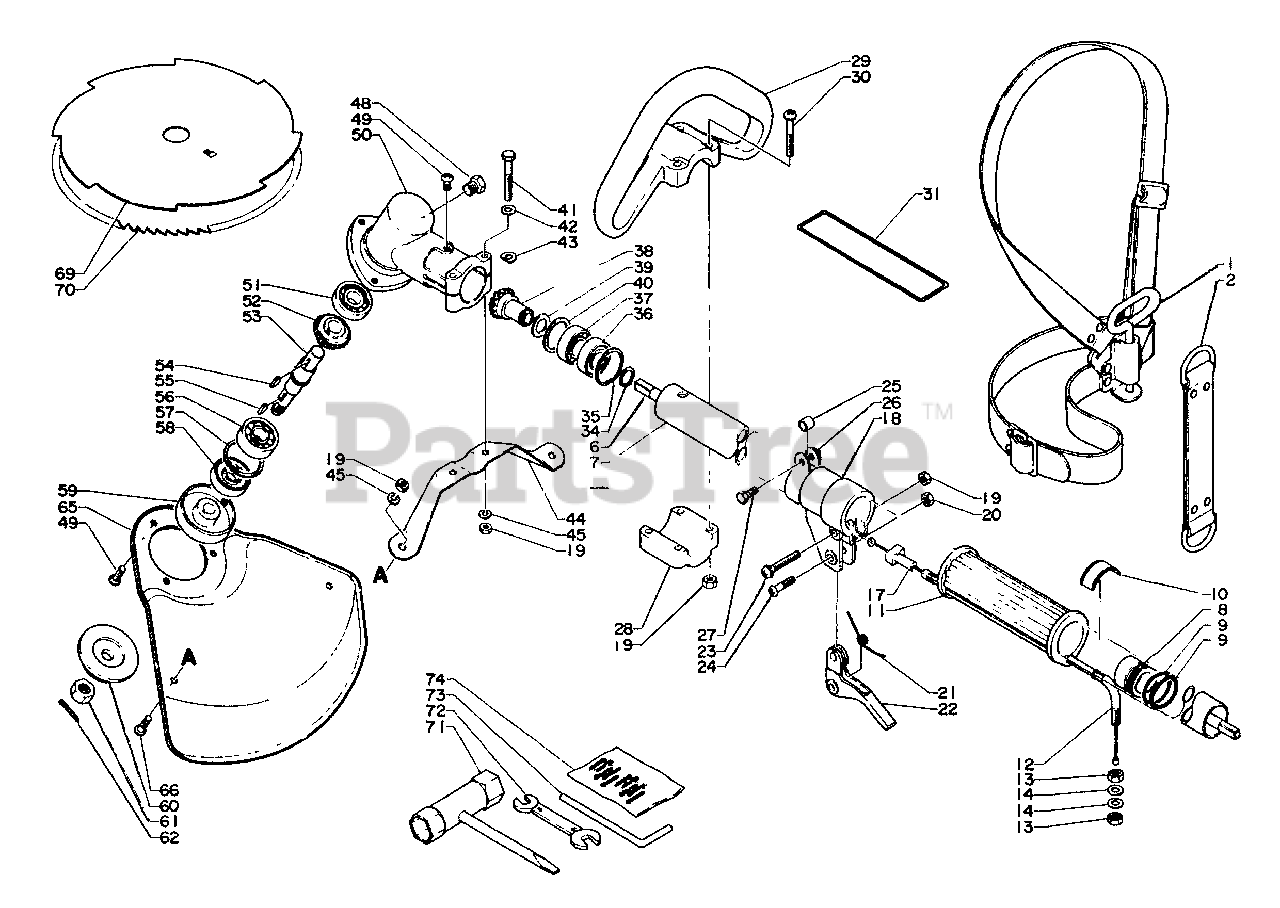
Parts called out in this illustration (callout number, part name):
1	SHOULDER STRAP ASSY
2	STRAP
6	DRIVESHAFT
7	MAIN PIPE ASSY
8	STOPPER
9	O-RING - 22
10	LABEL - ALIGNMENT
11	GRIP
12	CABLE, THROTTLE
13	LOCKNUT - 6
14	WASHER - 6
17	GUIDE, CABLE
18	BRACKET, TRIGGER
20	LOCKNUT - 5
21	SPRING, TRIGGER
22	TRIGGER, THROTTLE
23	SCREW - 5X30
24	SCREW - 5X30
27	BOLT - 5X16
28	BRACKET, HANDLE
29	LOOP HANDLE ASSY
30	SCREW - 5X35
31	LABEL - CAUTION
34	RING, RETAINING - 12
35	RING, RETAINING - 28
36	BEARING, BALL - 6001
37	BEARING, BALL - 6001
38	GEAR SET
41	BOLT - 5X40
42	WASHER - 5
44	BRACKET, SHIELD
45	LOCKWASHER - 5
48	BOLT - 8X8
49	SCREW - 5X10
50	CASE, GEAR
51	BEARING, BALL - 6000
52	GEAR SET
53	DRIVESHAFT
56	BEARING, BALL - 6201
57	RING, RETAINING - 32
58	SEAL, OIL
59	ADAPTOR, BLADE - UPPER
60	ADAPTOR, BLADE - LOWER
61	NUT - 10 -- LEFT HAND
62	PIN, SPLIT - 2X22
64	SCREW - 5X10
65	SHIELD, DEBRIS - METAL
66	SCREW - 5X8
69	BLADE - 8 TOOTH -- 10" (25cm)
70	SAW, CIRCULAR
71	T-WRENCH
72	SPANNER - 8X10mm
73	LOCKING TOOL
74	PIN, SPLIT - 2X22
